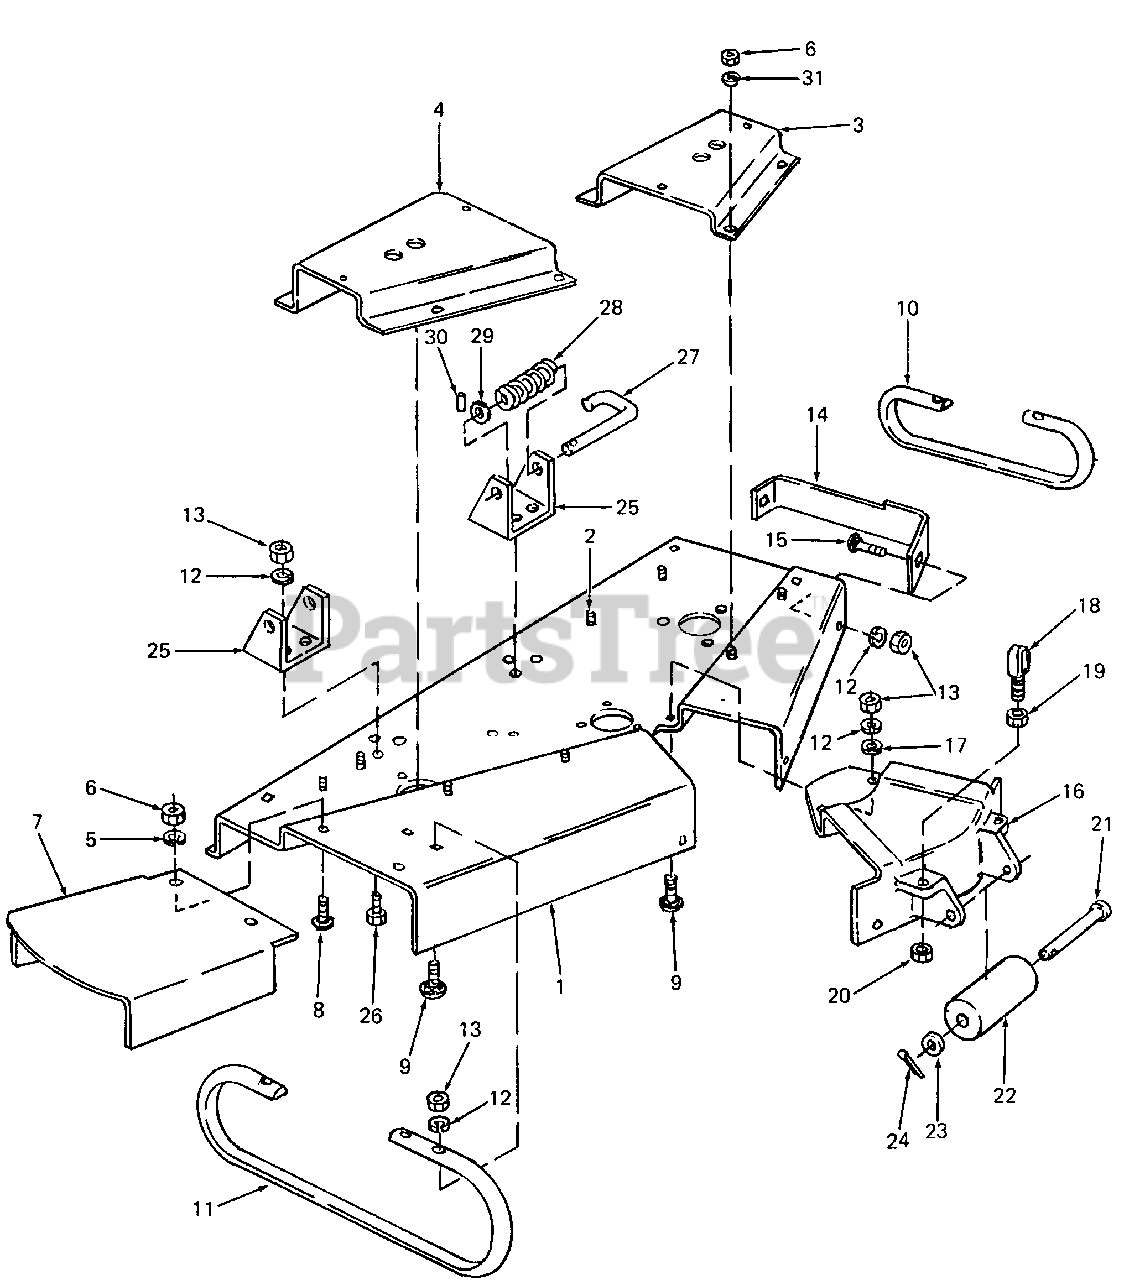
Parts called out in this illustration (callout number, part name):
1	Housing Assy, 38" Mower w/Graphics
2	Screw, Hex Cutting, 5/16-18 X .62 Lg
3	Cover, LH - Belt
4	Cover, RH - Belt
5	Washer, Lock, 5/16
6	Nut, Hex, 5/16-18 GR5
9	Bolt, Short Neck Carriage, 3/8-16 X 1.0 Lg GR5
13	Nut, Hex, 3/8-16 GR5
14	Housing, Side w/Graphic
15	Bolt, Carriage, 3/8-16 X .75 Lg
18	Hanger, Mower Support Front
19	Nut, Hex Jam, 5/8-11 GR5
20	Nut, Hex Insert Top Lock, 5/8-11 GR5
21	Pin, Clevis, 1/2 Dia X 7.0 Lg
22	Roller, Front
23	Washer, Flat, .510 X 1.0 X .06 Thk
24	Pin, Cotter, 3/6 Dia X 1.0 Lg
27	Pin, Mower Support
28	Spring, Compression
29	Washer, Flat, .531 X .930 X .050 Thk
30	Pin, Spirol Spring, 3/16 Dia X .75 Lg
31	Washer, Flat, .34 X .88 X .062 Thk
